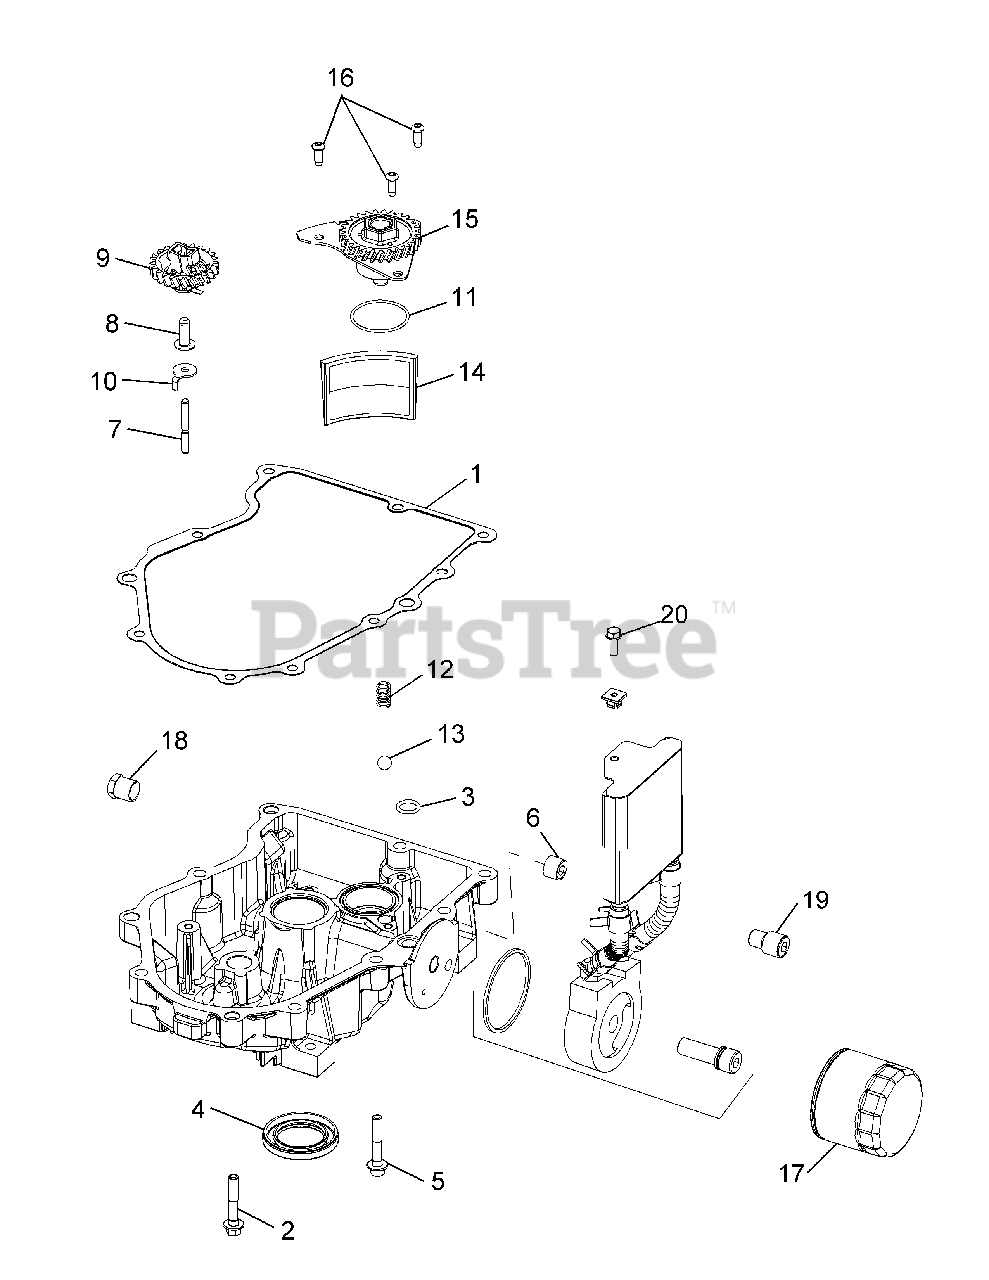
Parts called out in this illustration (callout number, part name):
1	Oil Pan Gasket
2	Flange Screw, M8 x 1.25 x .45
6	Pipe Plug, 3/8
7	Governor Gear Shaft
8	Governor Regulating Pin
9	Governor Gear Kit w/Pin
11	O-Ring (1.78" Dia.)
12	Compression Spring
13	Pressure Relief Ball
15	Oil Pump Assembly
16	Button Head Screw
18	Pipe Plug, 3/8
19	Oil Filter Nipple
20	Tap Screw, M6 x 1.7 x 18
